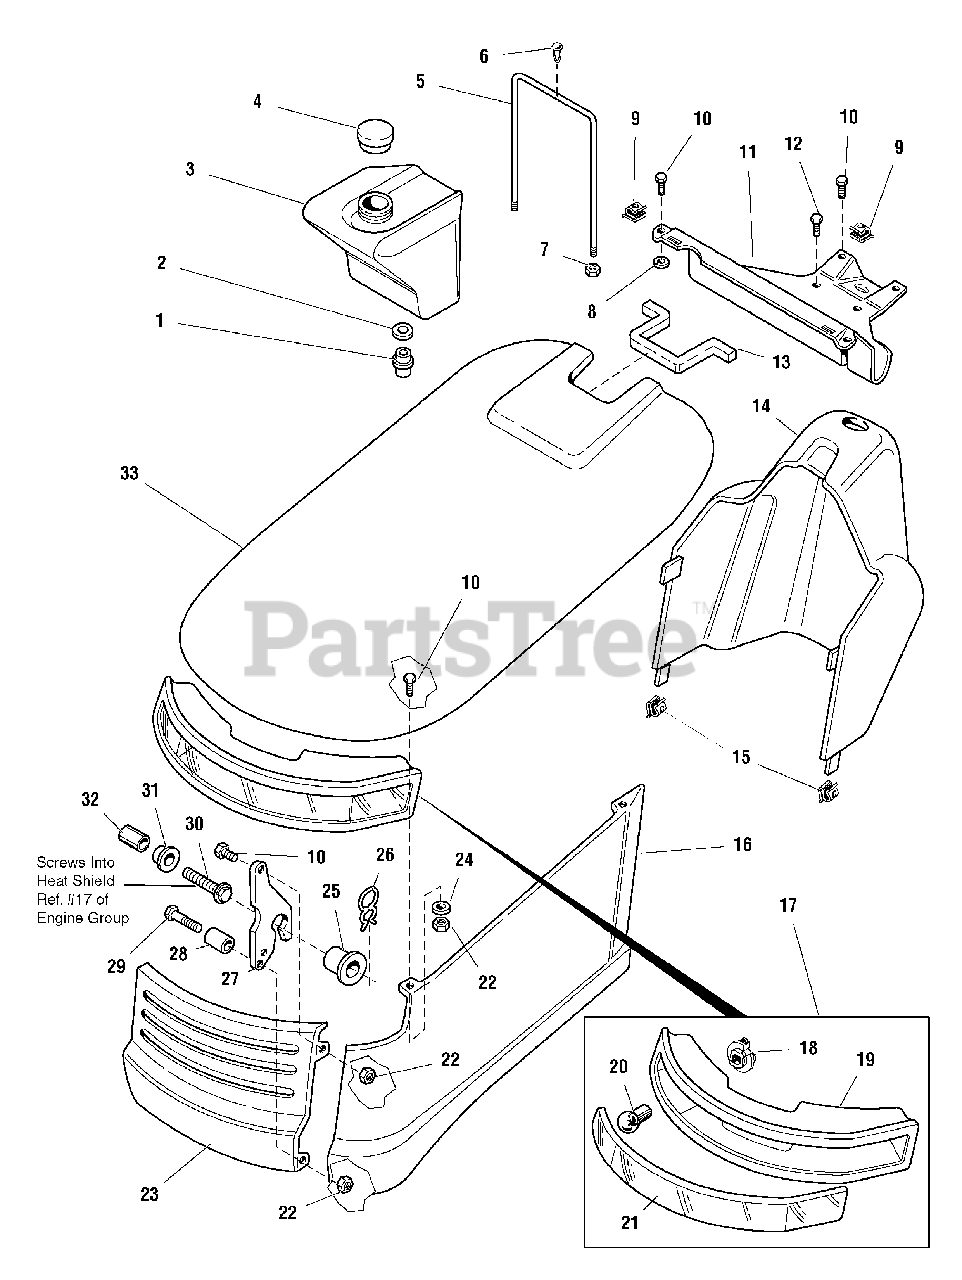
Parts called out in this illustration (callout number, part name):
1	FITTING, Fuel
2	GROMMET, Fuel Fitting
4	CAP, Fuel Tank
6	FASTENER, Plastic, Ratchet
7	NUT, Hex Nylon Lock, 5/16-18
8	WASHER, 1/4
9	PAL NUT, 1/4-20
10	CAPSCREW, Whiz Lock Hex Hd, 1/4-20 x 5/8
12	CAPSCREW, Taptite Hex Washer Hd, 1/4-20 x 1/2
13	GROMMET, Strip
16	PANEL, Side, LH, Orange
16	PANEL, Side, LH, Red
17	LIGHT BAR ASSEMBLY
18	SOCKET, Bulb
20	BULB, #1156
22	NUT, Hex, Nylon Lock, 1/4-20
23	GRILLE, Orange
23	GRILLE, Red
24	WASHER, Plain, 1/4
25	SPACER, Plastic, Hood Pivot
26	CLIP, Pivot Spacer Retaining
27	HINGE, Hood
29	CAPSCREW, Hex Hd, 1/4-20 x 1-1/2
30	CAPSCREW, Whiz Lock Hex Hd, 5/16-18 x 1-1/4
31	SPACER, Steel, Hood Pivot, Grooved
32	SPACER, Steel, Hood Pivot
33	HOOD, Orange
